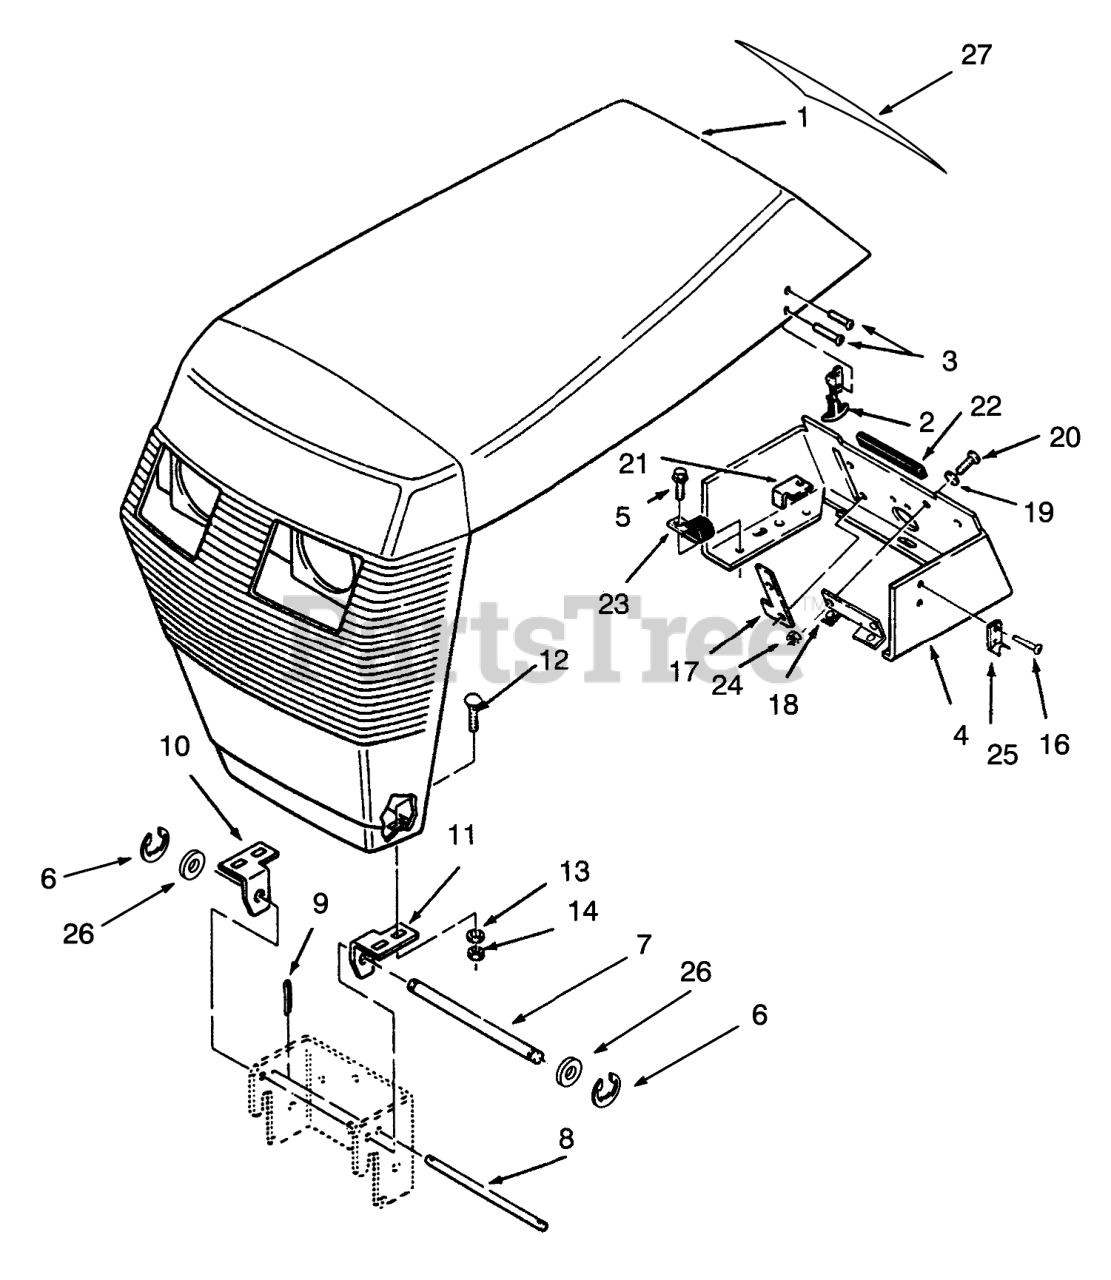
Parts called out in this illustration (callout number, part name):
1	Hood (Incl. Ref. #27)
2	Handle Assembly (Incl. Ref. #25)
3	RIVET-POP
4	Console
5	SCREW
6	RING-RETAINING
7	ROD-GRILL PIVOT
8	ROD-HOOD STOP
9	Cotter Pin
10	BRACKET-GRILL, R H
11	BRACKET-GRILL, LH
12	SCREW-CARR
13	WASHER-FLAT
14	NUT-LOCK
16	POPRIVET 1/8X 1/8 BK
17	Washer
18	BRACKET
19	Washer-Lock
20	SCREW-PAN
21	STOP-PTO
22	EDGING-CONSOLE
23	J-CLIP
24	Nut
25	KEEPER-LATCH
26	NYLINER BUSHING
27	Decal-Danger
